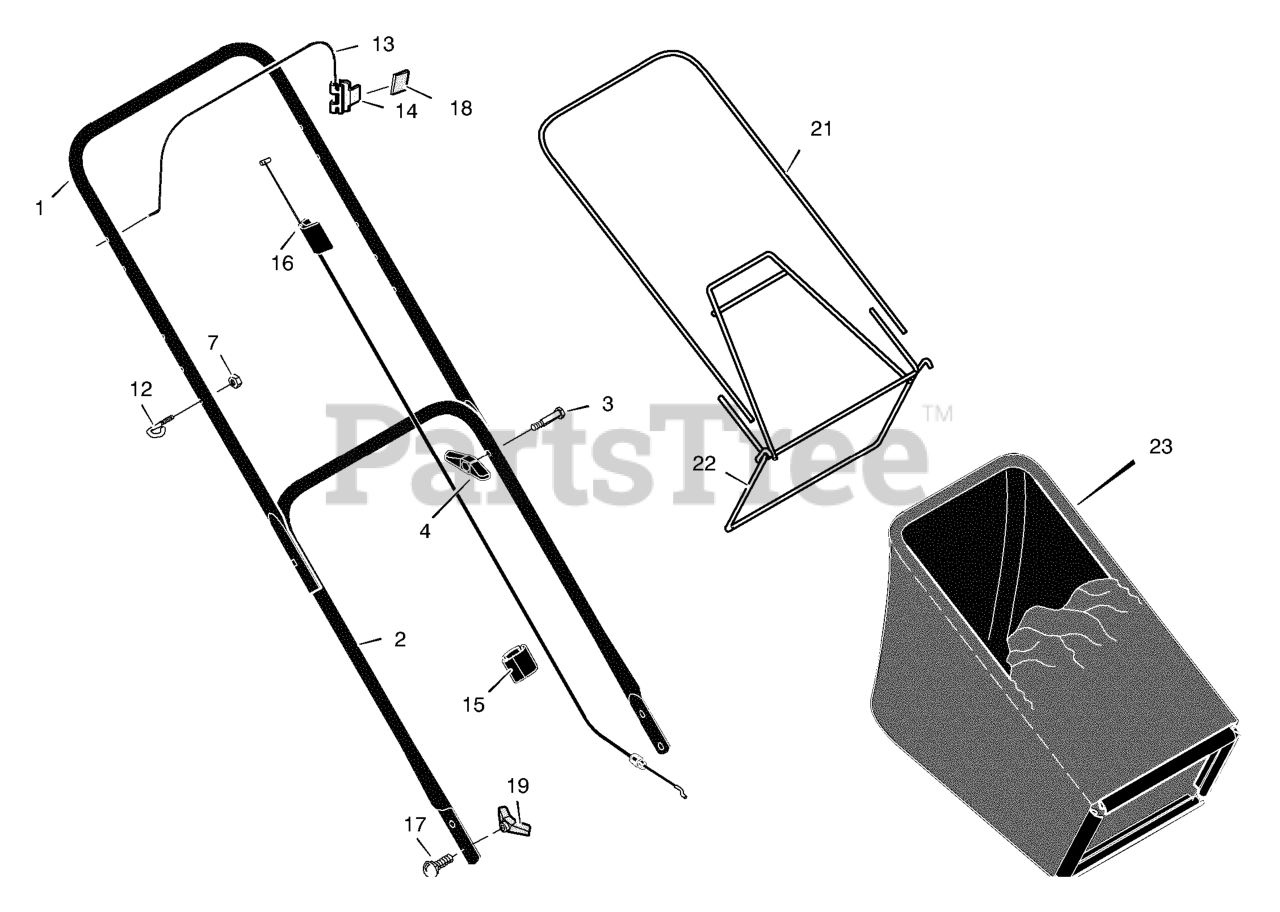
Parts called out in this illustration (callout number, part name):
1	Handle, Upper (Black)
2	Handle, Lower (Black)
4	Knob, Plastic
7	Locknut
12	Guide, Rope
13	Lever, Engine Stop
14	Bracket, Stop Lever
15	Clip, Cable
16	Engine Stop Cable
17	Bolt, Carriage
19	Knob, Plastic
21	Tube, Bag
22	Frame Assembly
23	Bag, Cloth - Black
